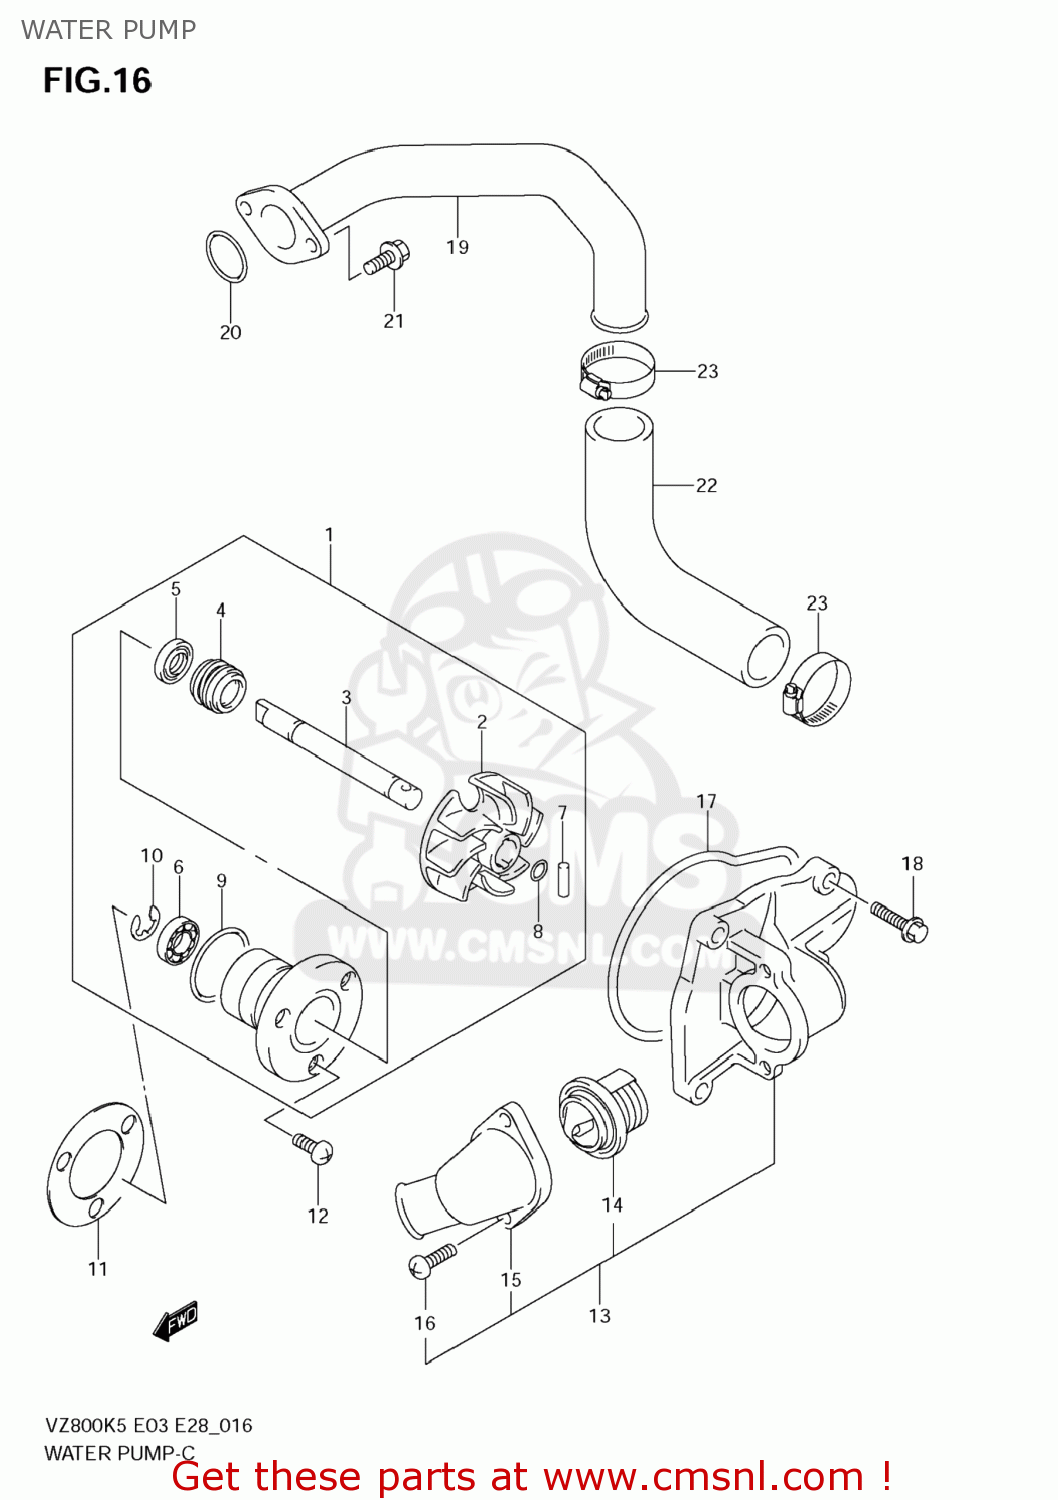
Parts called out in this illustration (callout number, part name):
1	PUMP ASSY,WATER
2	IMPELLER
3	SHAFT
4	SEAL,MECHANICAL
5	SEAL,OIL(10X21X5)
6	BEARING(10X22X6)
7	PIN
8	O RING
9	O RING
10	E RING
11	GASKET,WATER PUMP (NAS)
12	SCREW
13	CAP ASSY,WATER PUMP
14	THERMOSTAT,WATER
15	CONNECTOR
16	SCREW
17	O RING,WATER PUMP CAP
18	BOLT
19	PIPE,CYLINDER INLET
20	O RING(D:2.3,ID:24.4)
21	BOLT
22	HOSE,WATER PUMP OUTLET
23	CLAMP
